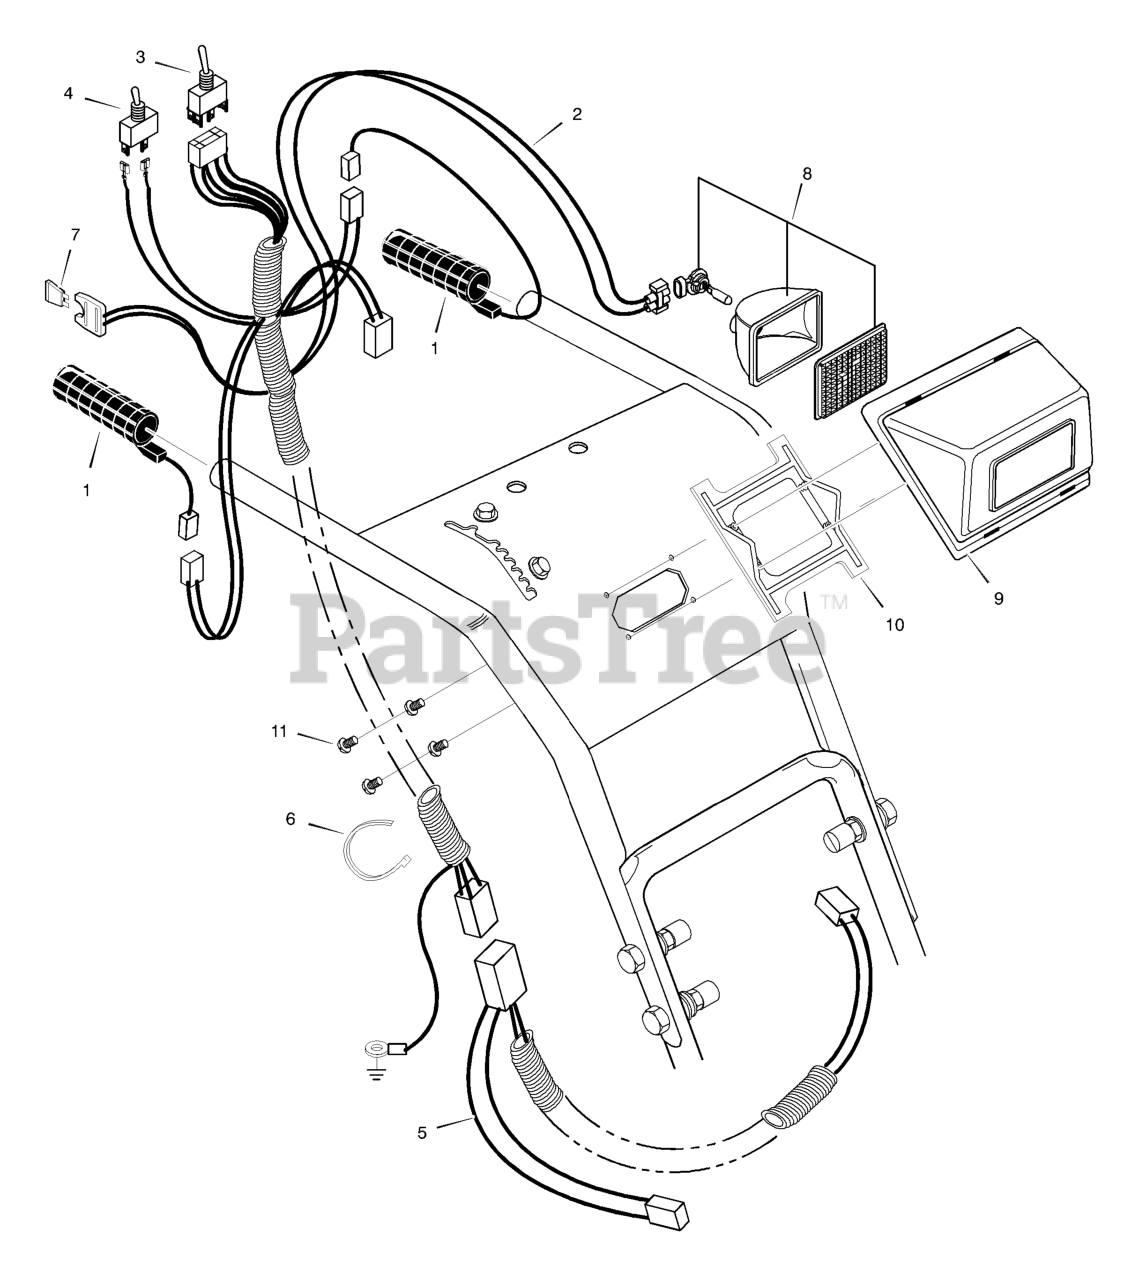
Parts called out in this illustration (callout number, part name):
1	GRIP, HEATED
2	WIRE, HARNESS
3	SWITCH, CHUTE ROTATION
4	SWITCH, HEATED GRIP
5	WIRE HARNESS, LOWER
6	TIE, CABLE
7	FUSE, 7.5 AMP AUTOMOTIVE
8	HEADLIGHT ASSEMBLY *
9	CASE, HEADLIGHT
10	BRACKET, HEADLIGHT
